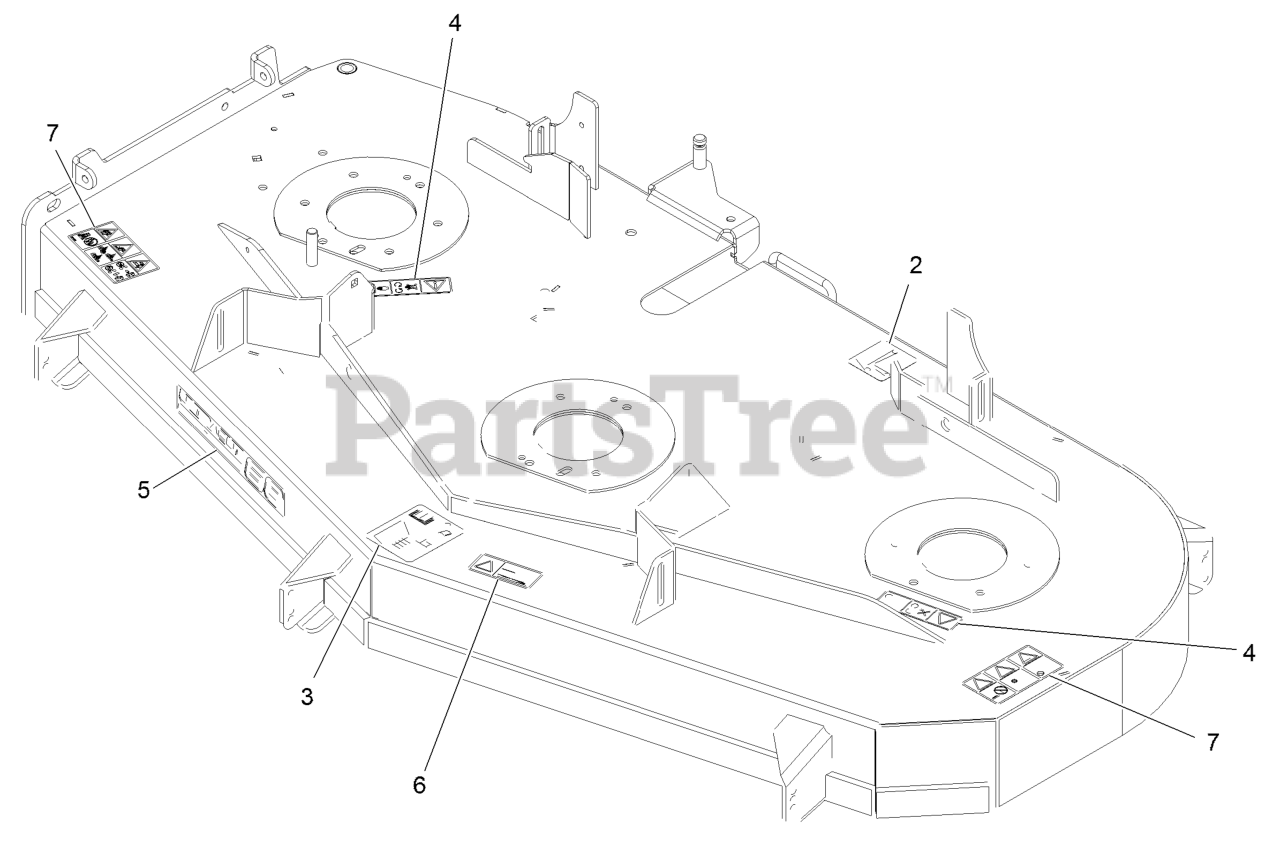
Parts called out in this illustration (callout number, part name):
2	DECAL-ROUTING, BELT
3	DECAL-ROLLER, ANTI-SCALP
4	DECAL-COVER, MISSING
5	DECAL-ULTRACUT 60 SERIES
6	DECAL-BOLT TORQUE
7	DECAL-DANGER THROWN OBJECTS
